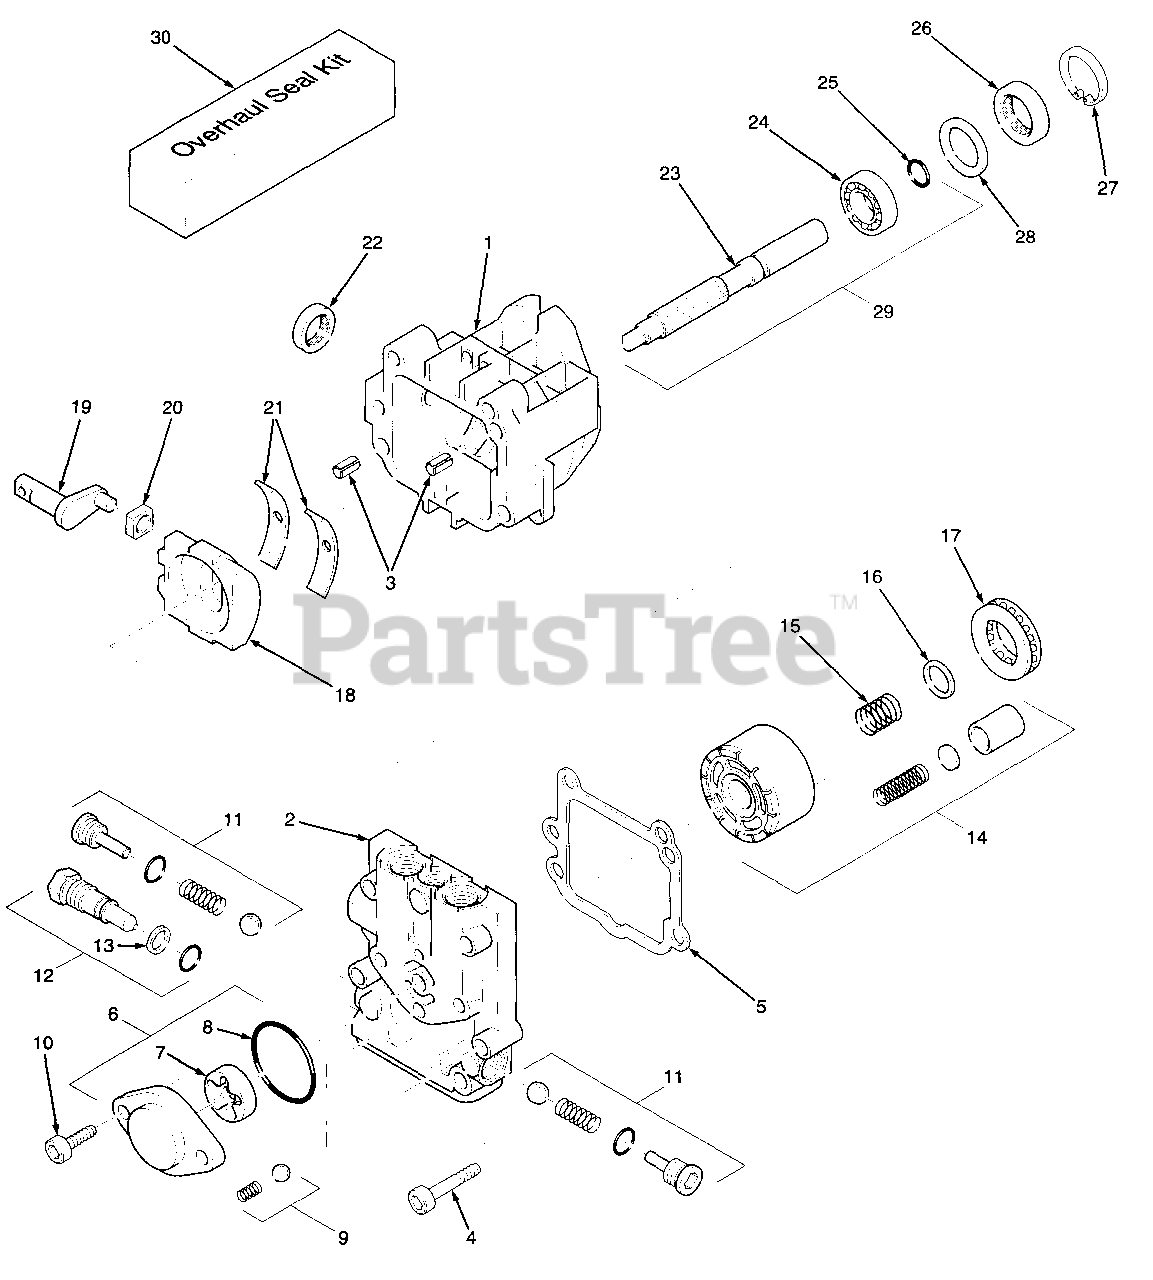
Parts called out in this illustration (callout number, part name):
1	Housing Kit
2	End Cap
3	Straight Headless Pin
4	Socket Head Screw
5	End Cap Gasket
6	Charge Pump Kit
7	Gerotor Assembly
9	Charge Relief Valve Kit
10	Socket Head Screw
11	Check Valve Kit
12	Bypass Valve Kit
13	Backup Ring
14	Cylinder Block Kit
15	Block Spring
16	Block Thrust Washer
17	Roller Thrust Bearing
18	Swash Plate
19	Trunnion Arm
20	Guide Slot
21	Cradle Bearing
23	Pump Shaft
24	Ball Bearing
25	Retaining Ring
27	Retaining Ring
28	Spacer
29	Shaft Kit
30	Overhaul Seal Kit
